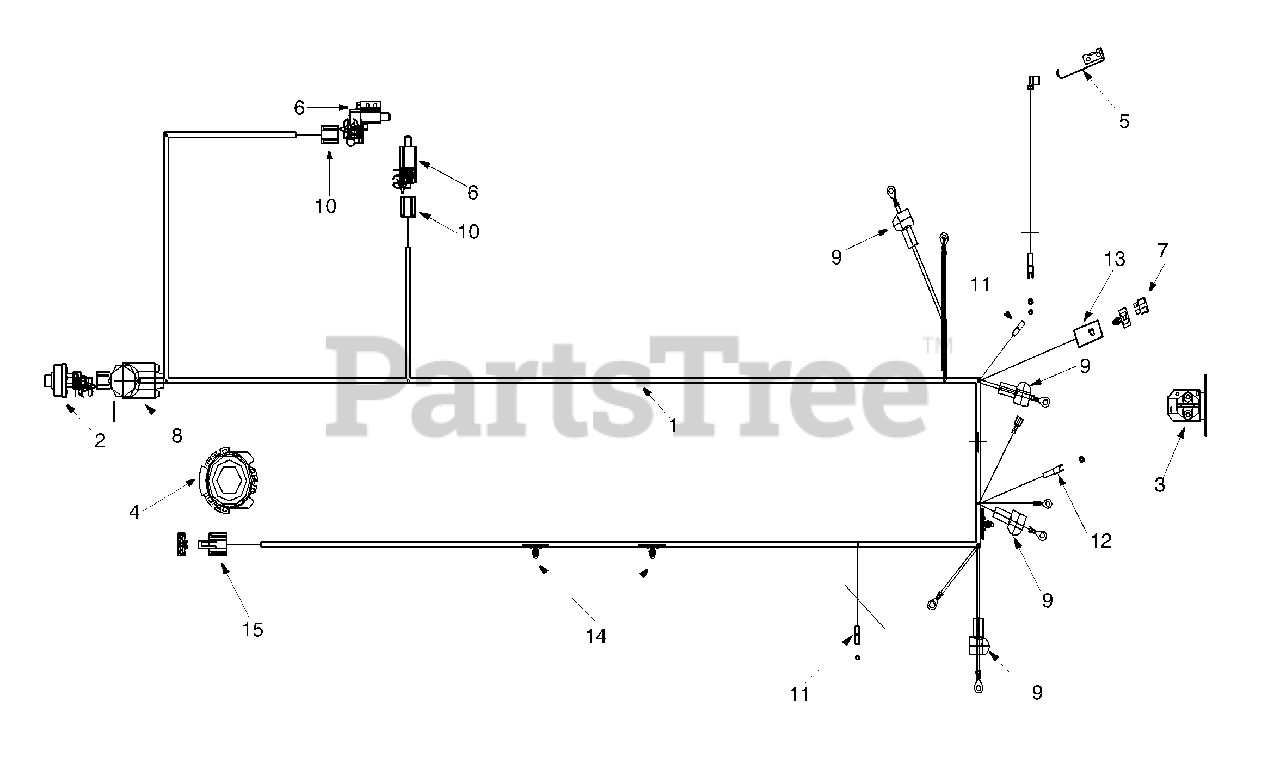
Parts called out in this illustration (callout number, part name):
1	Harness Assembly w/o relays
2	Ignition Switch: 5 Pin
3	Solenoid: 12 V. 100 amp.
4	Seat Switch
5	Spring Switch
6	Interlock Switch
7	Fuse: 20 amp.
8	Battery Cover
9	Battery Cover: Red
10	Connecter
11	Connecter
12	Connecter
13	Fuse Holder w/Clip
14	Harness Clip
15	Connecter
